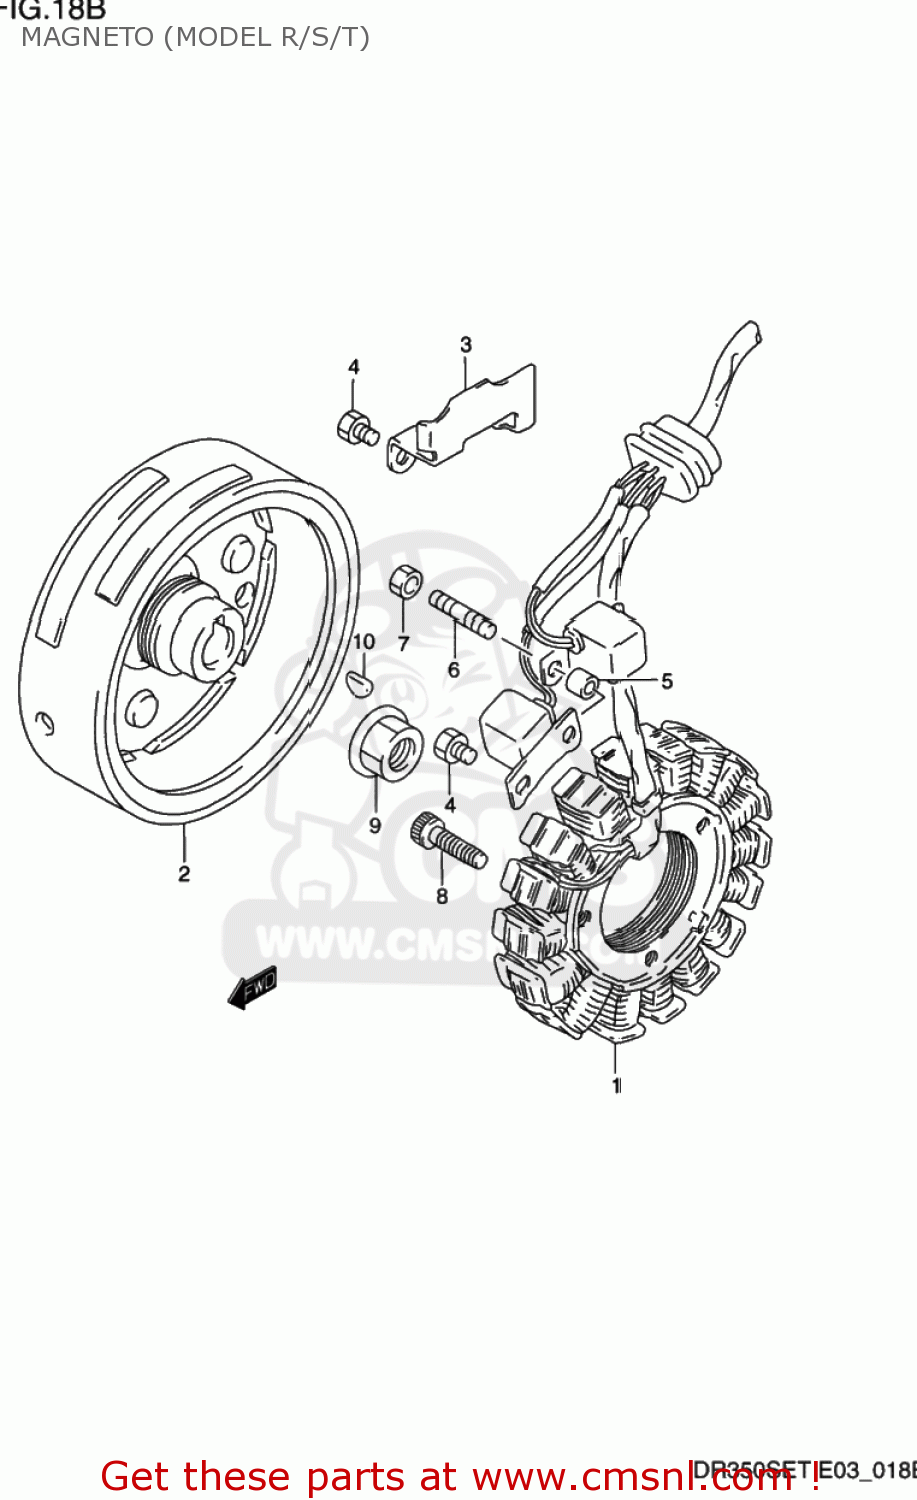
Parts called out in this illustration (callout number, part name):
1	STARTER ASSY
2	ROTOR ASSY
3	CLAMP,MAGNETO LEAD WIRE
4	BOLT(5X10)
5	SPACER (5.5X9.5X6.5)
6	BOLT,STUD(5X18)
7	NUT
8	BOLT,CL.COVER
9	NUT
10	KEY
